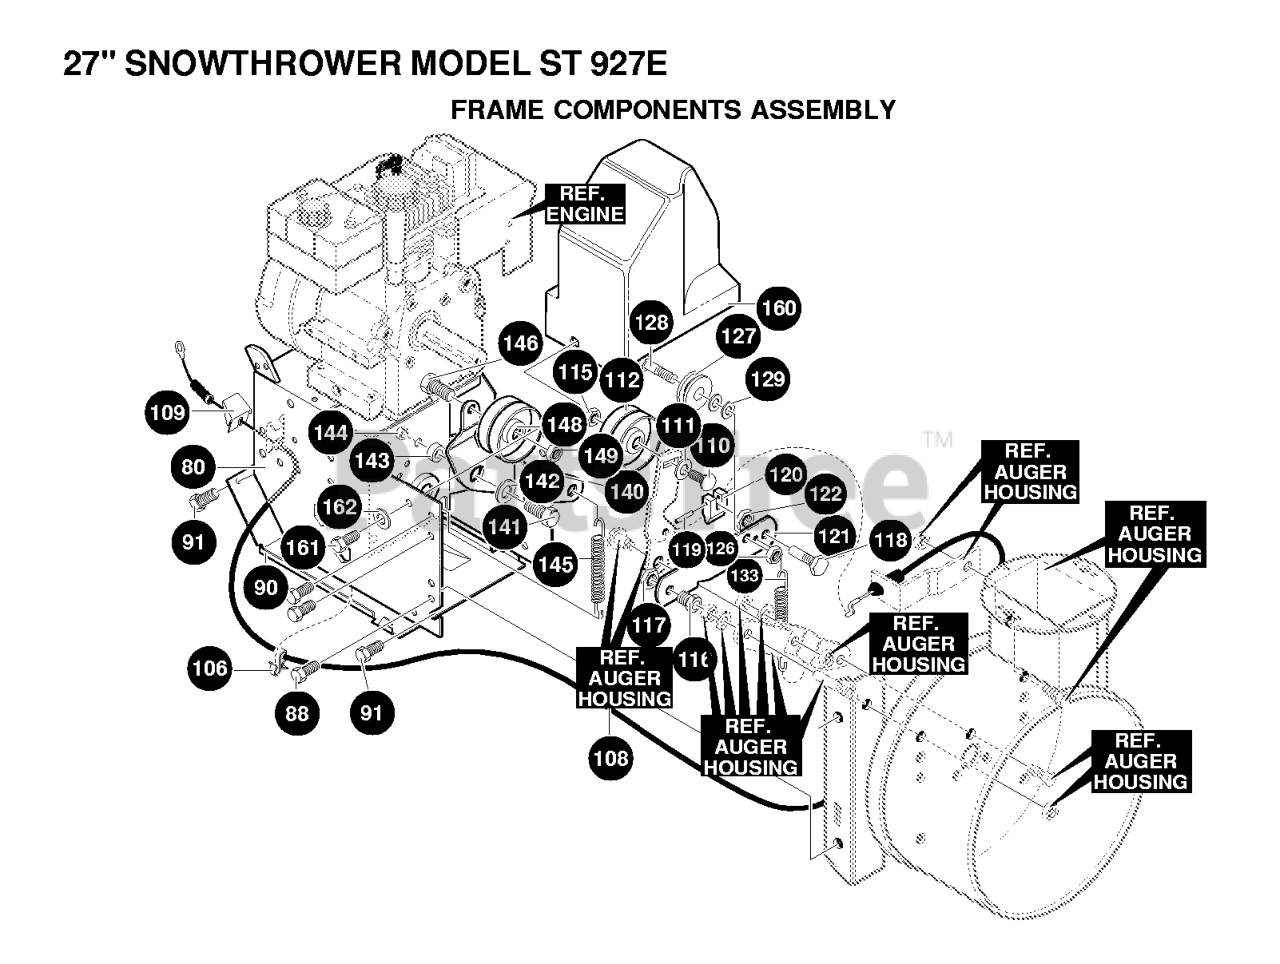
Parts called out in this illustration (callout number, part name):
14	IDLER PULLEY
80	FRAME, ASSY
88	SCREW, 5/16-18X .50 WAHHT
90	COVER, BOTTOM WHEEL DRIVE
106	CLIP, CABLE TINN
108	CABLE, AUGER
109	SHIELD, CABLE GROUND
110	CARR. BOLT, 3/8-16X1.25
111	WASHER, FLAT .506X .75X.
112	IDLER PULLEY
116	BOLT. BRAKE ARM 9/16-18
117	NUT, 9/16-18 HEX
118	BOLT-BRAKE ARM ADJ.
121	BRACKET, PUCK
122	NUT, 1/2-20 JAM
126	NUT, 1/4-20 REGHEXCTRLK
127	PULLEY, ALUMINUM
128	BOLT, SH 1/4-20
129	WASHER, FLAT .250X .56X.
133	SPRING, IDLER
141	SCREW, 5/16-18X .75 HHC
146	SCREW, 3/8-16 X 1.25
160	COVER, BELT
162	WASHER, FLAT .281X .63X.
